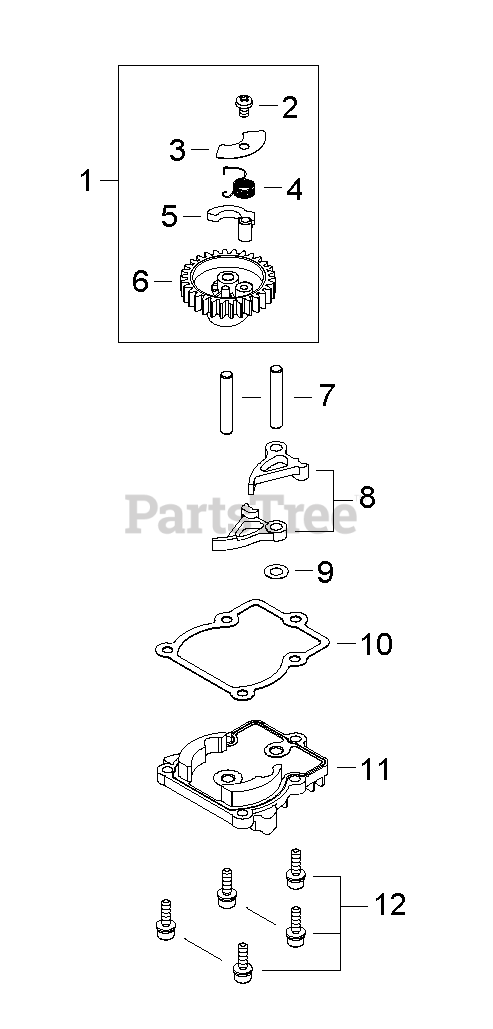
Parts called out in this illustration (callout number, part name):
1	CAM GEAR ASSY
2	SCREW, TAPPING 4×6
3	PLATE, COVER
4	SPRING
5	WEIGHT
6	GEAR, CAM
7	PIN, LOCATING Ø5×29.8 MM
8	FOLLOWER, CAM
9	WASHER 5 MM
10	GASKET, CAM GEAR
11	COVER, CAM GEAR
12	BOLT M4×14
